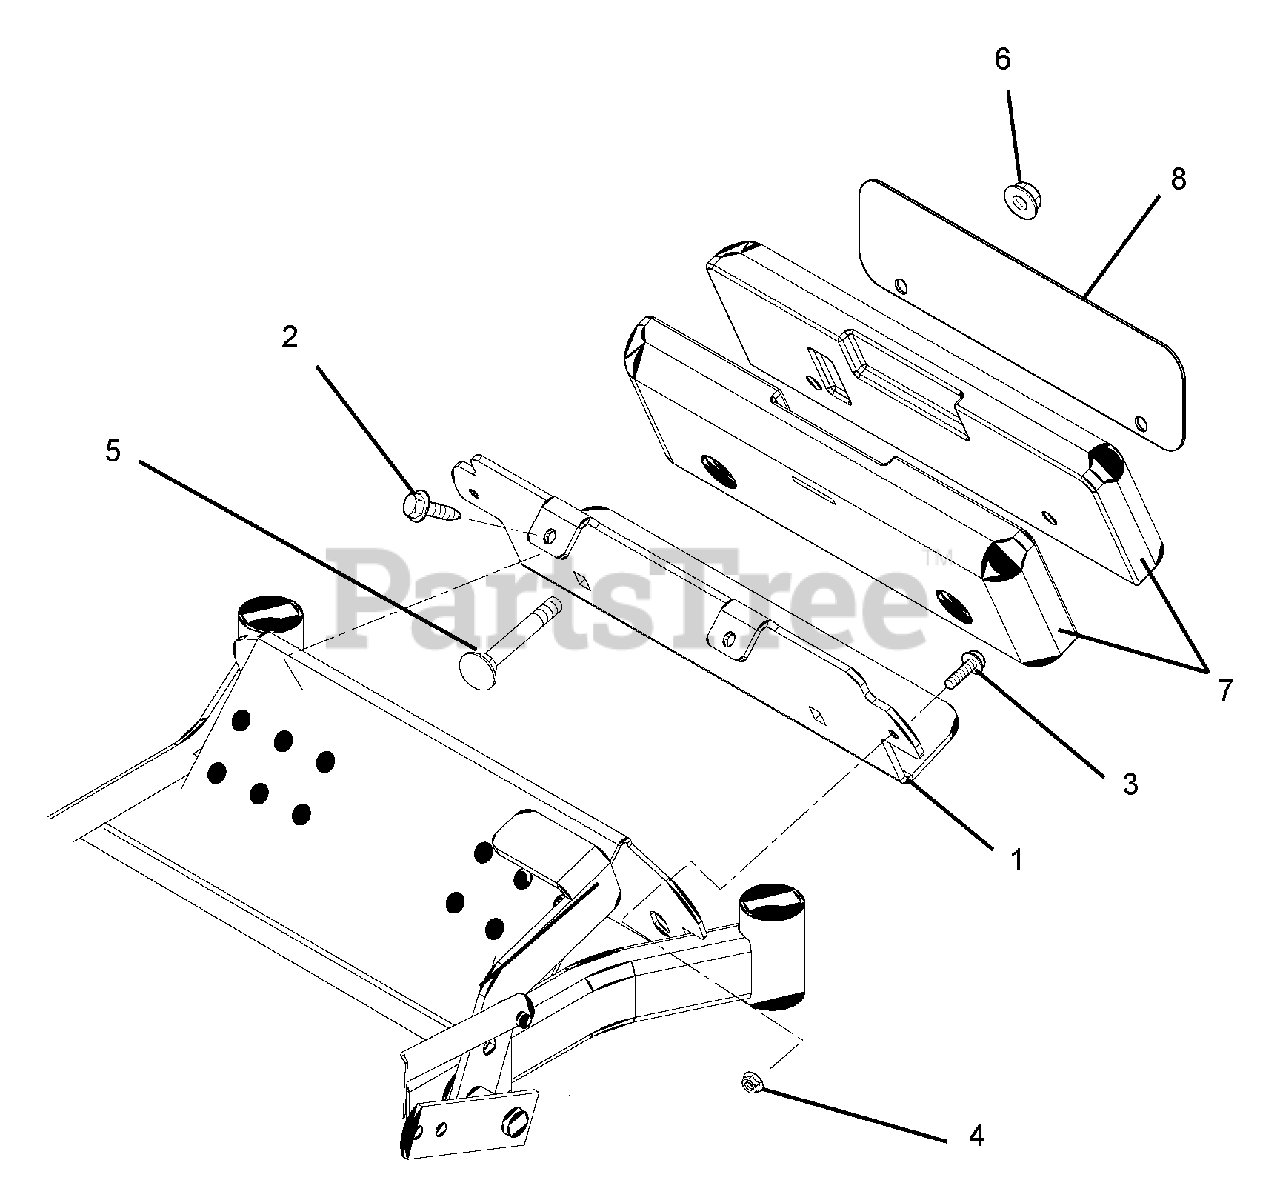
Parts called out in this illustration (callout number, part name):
1	BKRT, CZ WEIGHT
2	@SCR-TAP .38-16X.75 HWH TR YWZ
3	@BLT-HEX .38-16X1.25 GR5 YWZC
4	@NUT-LK-TOP-FLG .38-16 YWZC
5	BLT-RDHDSQNK .50-13X5.00 GR5YZ
6	@NUT-LK-TOP-FLG .50-13 YWZC
7	WEIGHT, CAST IRON
8	PANEL, DECAL
